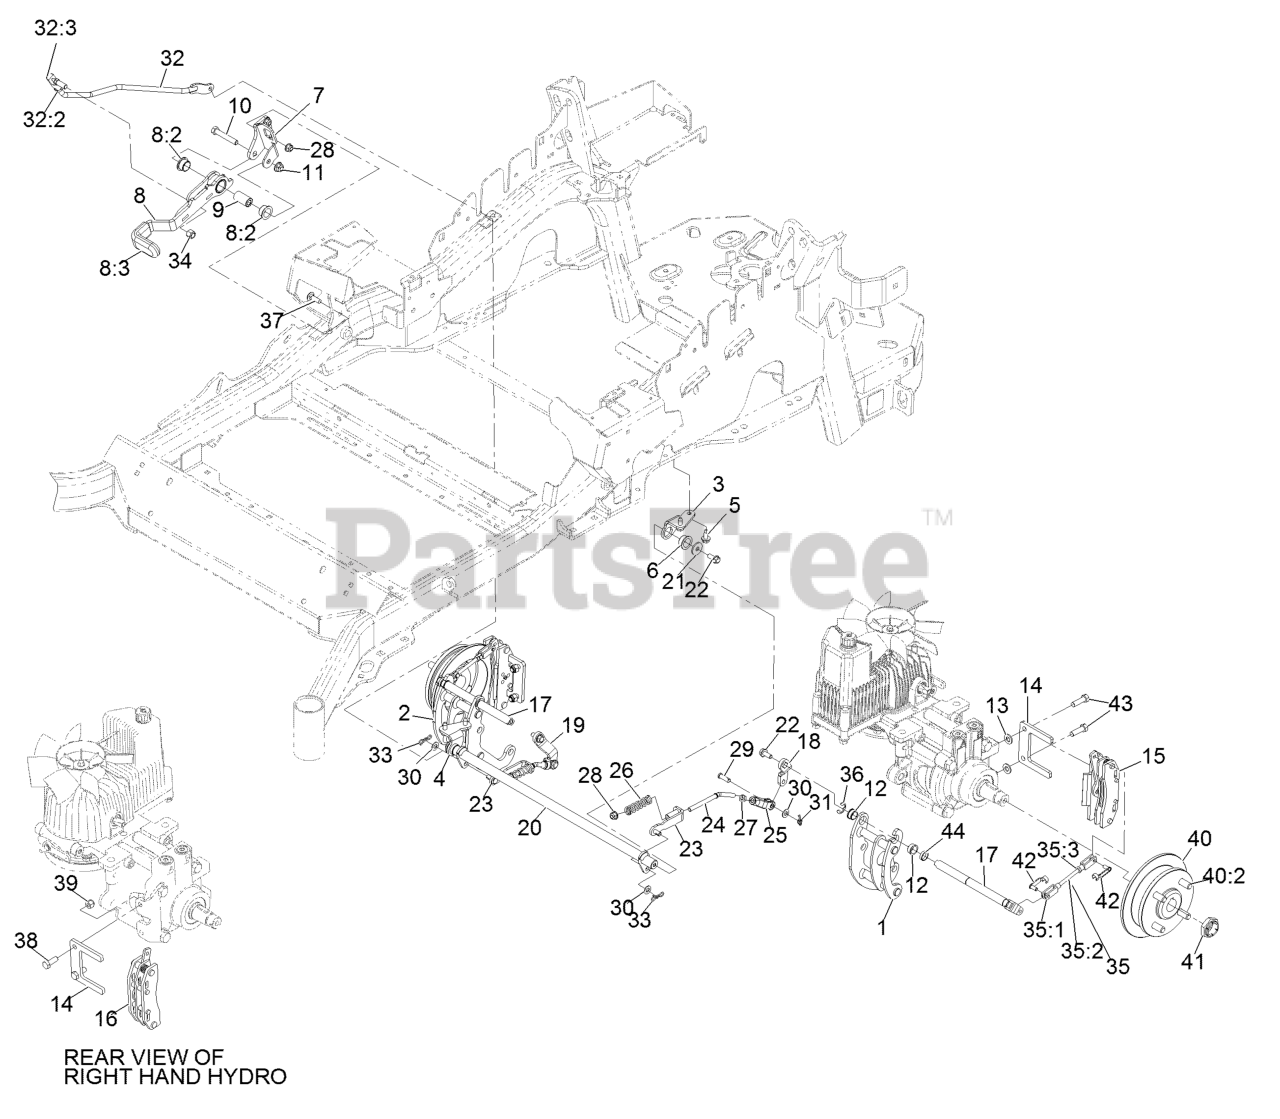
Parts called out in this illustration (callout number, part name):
1	MOUNT-BELLCRANK, LH
2	MOUNT-BELLCRANK, RH
3	MOUNT-PIVOT, LH
4	MOUNT-PIVOT, RH
5	Screw-HWH 5/16-18 X 3/4 Tf
6	BUSHING-FLANGE
7	BRACKET-MOUNT
8	BRAKE LEVER ASM
8:2	BUSHING-FLANGE
8:3	GRIP-LEVER
9	HANDLE-PIVOT, BRAKE
10	SCREW-HH
11	NUT-HF, NI
12	BUSHING
13	WASHER-FLAT
14	PLATE-MOUNT, BRAKE
15	CALIPER-BRAKE
16	CALIPER-BRAKE, RH
17	BELLCRANK
18	ARM-INNER, LH
19	ARM-INNER, RH
20	SHAFT-CROSS
21	WASHER-FLAT
22	SCREW-HHF
23	BRACKET-L
24	LINKAGE-MID
25	YOKE-OFFSET
26	SPRING-COMPRESSION
27	NUT-JAM
28	NUT-HF, NI
29	PIN-CLEVIS
30	WASHER-PLAIN
31	PIN-COTTER, LOCKING
32	FRONT LINKAGE ASM
32:2	END-TIE ROD, RH
32:3	NUT-HJ
33	PIN-COTTER, LOCKING
34	NUT-LOCK
35	REAR LINKAGE ASM
35:3	NUT-JAM
37	BOLT-CARR
38	SCREW-HH
39	NUT-LOCK, NI
40	WHEEL HUB ASM
40:2	STUD-WHEEL
41	LOCKNUT
42	PIN-CLEVIS, SPRING
43	SCREW-LOCK, PATCH
